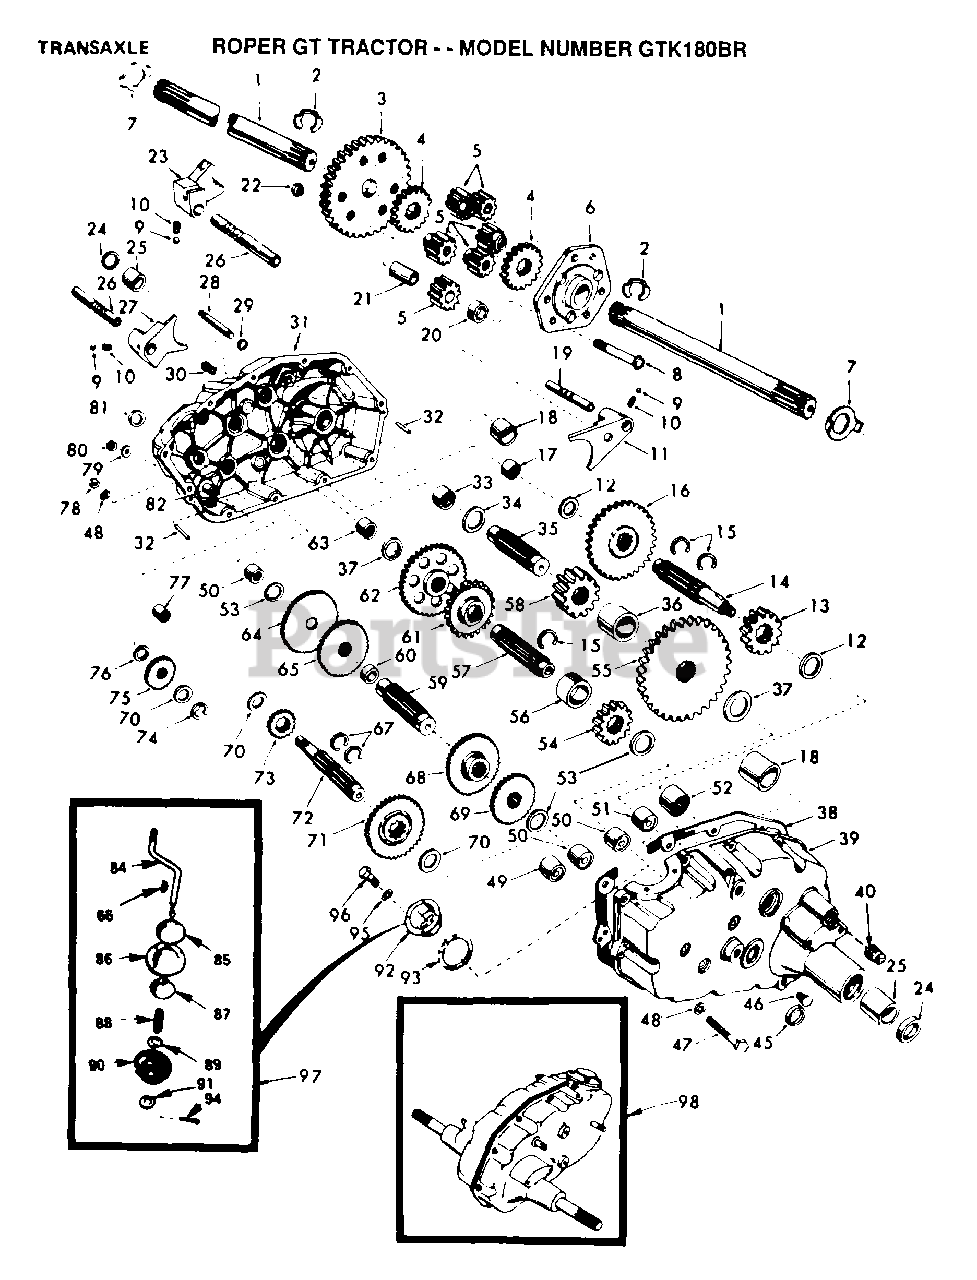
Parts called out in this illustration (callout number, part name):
1	SHAFT.AXLE.T
3	FINAL GEAR T
4	DIFF GEAR T
5	DIFF PINION T
6	DIFF CARRIER T
8	BOLT
11	SHIFT FORK T
12	WASHER .T
13	RED PINION T
14	GEAR SHAFT T
15	SNAP RING T
16	GEAR T
17	"T, BEARING"
18	BEARING
19	SHAFT
20	SPACER T
21	PINION RS
22	GRIPCO NUT
23	SHIFT FORK T
24	OIL SEAL STD
25	BRNG. T
27	FORK T
28	SHIFT SHAFT
30	VALVE M
31	GEARCASE RH
32	PIN T
33	NEEDLE BRNG T
34	RACE T
35	GEAR SHAFT T
37	RACE T
38	GASKET
39	GEARCASE LH
40	PLUG PIPE
45	SEAL T
47	HEX BOLT
49	"TI, BEARING"
50	NEEDLE BRNG T
51	NEEDLE BRNG T
52	"STD, BEARING"
53	BRNG RACE
54	RED PINION T
55	RED GEAR T
56	PINION SPACER T
57	GEAR SHAFT T
58	FINAL PINION T
59	GEAR SHAFT T
60	SPACER T
61	RED PINION T
62	RED GEAR T
63	RACE T
64	LOW SPEED GEA T
65	REVERSE GEAR T
66	KEY T
67	RING STD
68	INTERMED GEAR T
70	"T, BEARING"
71	CLUSTER GEAR T
72	INPUT SHAFT T
73	LO SPEED PINION T
75	IDLER GEAR T
76	WASHER T
77	BRNG T
78	NUT.HEX.5/16-18
79	WASHER T
80	NUT
81	SEAL STD
84	GEAR SHIFT LVR T
85	CAP T
86	COVER AND PIN T
87	GUIDE BALL T
88	SPRING TI
89	WASHER
90	SEAL T
91	WASHER
92	GEAR SHIFT GA T
93	GASKET T
94	COTTER PIN
95	LOCKWASHER
96	BOLT
97	GEAR SHFT LVR T
